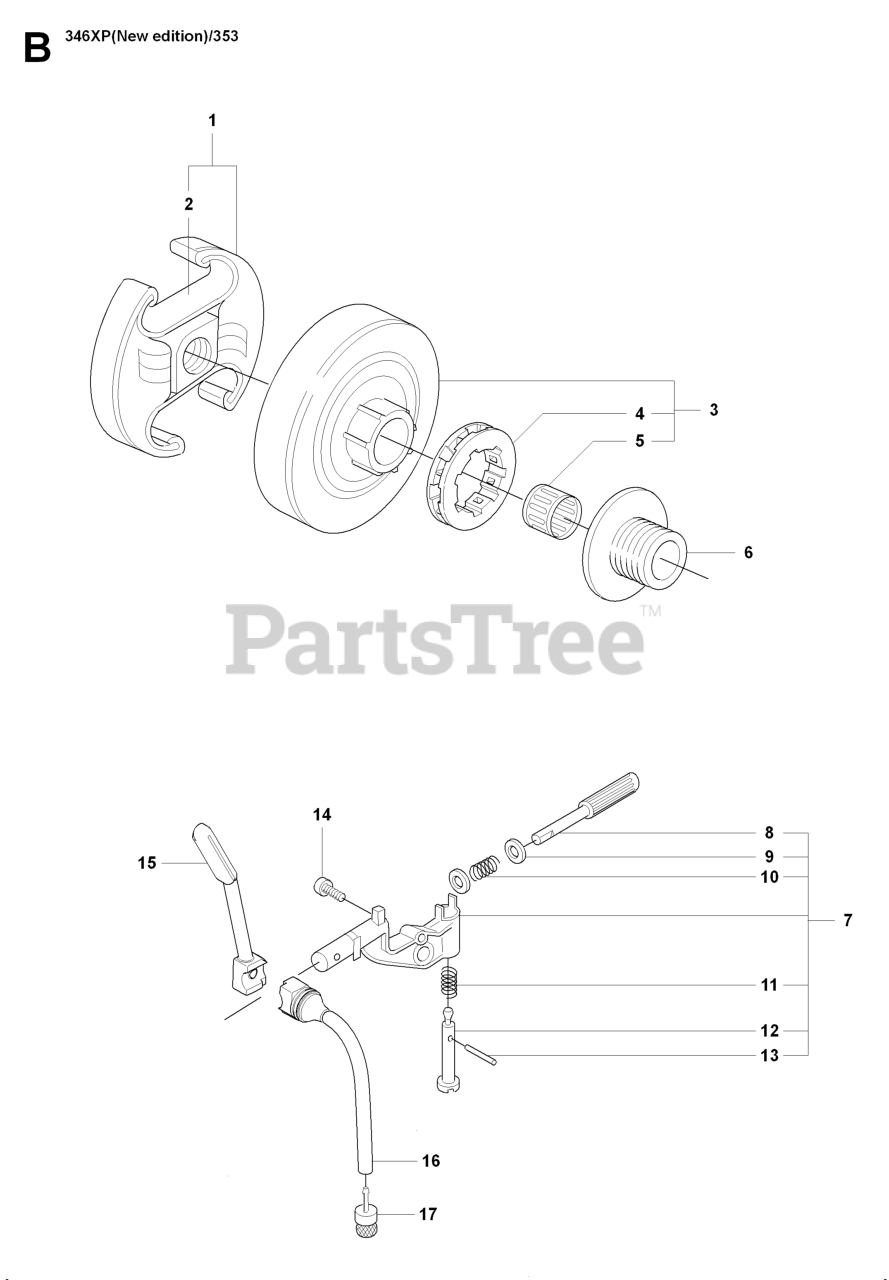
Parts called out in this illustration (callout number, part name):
3	%CLUTCH DRUM
4	RIM SPROCKET 7T .325
5	NEEDLE BEARING
6	%PINION
7	OIL PUMP ASSY
8	PUMP PISTON
15	OIL PRESSURE HOSE
16	RP HOSE
17	OIL PLUMMET
